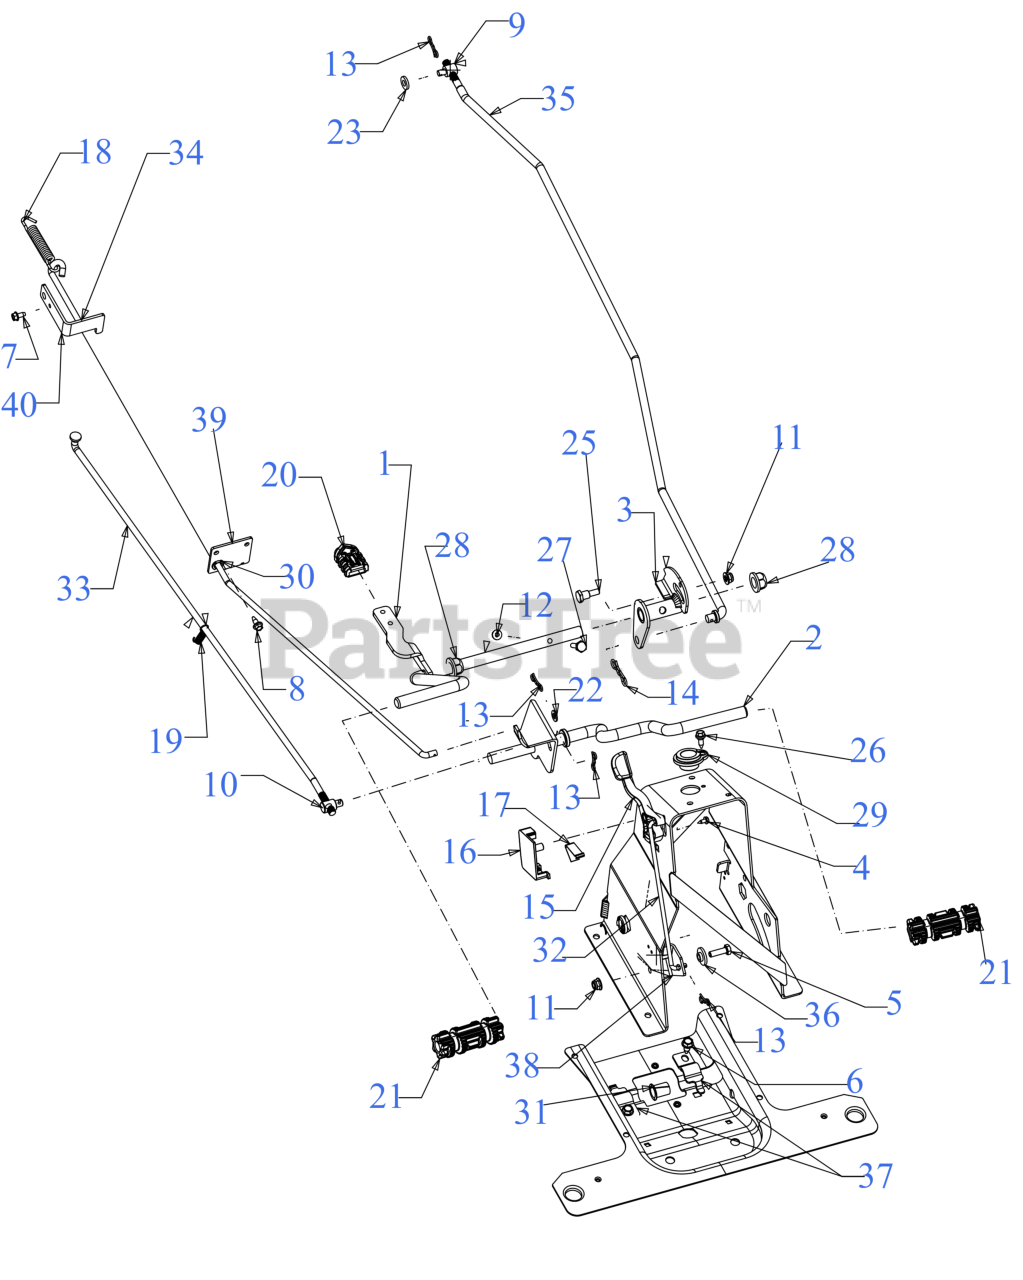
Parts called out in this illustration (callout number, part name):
2	BRAKE PEDAL
3	HYDRO PEDAL BELLCRANK ASSEMBLY
4	HEX SCREW AB-TAP #10 x .50
5	SCREW 5/16-18 x 1.0 GR5
6	SCREW 5/16-18 x .750
7	SCREW 1/4-20 X.500
8	SCREW 1/4-20X.625
9	FERRULE 3/8-16 x .312
10	FERRULE 3/8-24 x .375
11	FLANGE LOCK NUT 5/16-18
12	FLANGE LOCK NUT
13	BOW TIE COTTER PIN 1/4-5/16
14	BOW TIE COTTER PIN
15	PARK BRAKE LEVER
16	SPEED CONTROL COVER
17	SHIFT SPRING
18	EXTENSION SPRING .59 OD x 4.0
19	EXTENSION SPRING
20	REVERSE PEDAL PAD
21	BRAKE PEDAL PAD
22	FLAT WASHER
23	FLAT WASHER.344X.75X.1
25	SHOULDER SCREW 5/16-18 x .62 GR2
26	SHOULDER SCREW
27	SHOULDER SCREW .375 x .148
28	FLANGE BEARING
29	FLANGE BEARING
30	BUSHING .380 ID
31	FLANGE BEARING .626 x .938 x .875
32	SPEED SELECT ROD
33	HYDRO CONTROL ROD
35	DRIVE ROD (HYDRO)
36	SHOULDER SPACER
37	BRAKE SHAFT STRAP
38	PARK BRAKE BRACKET
